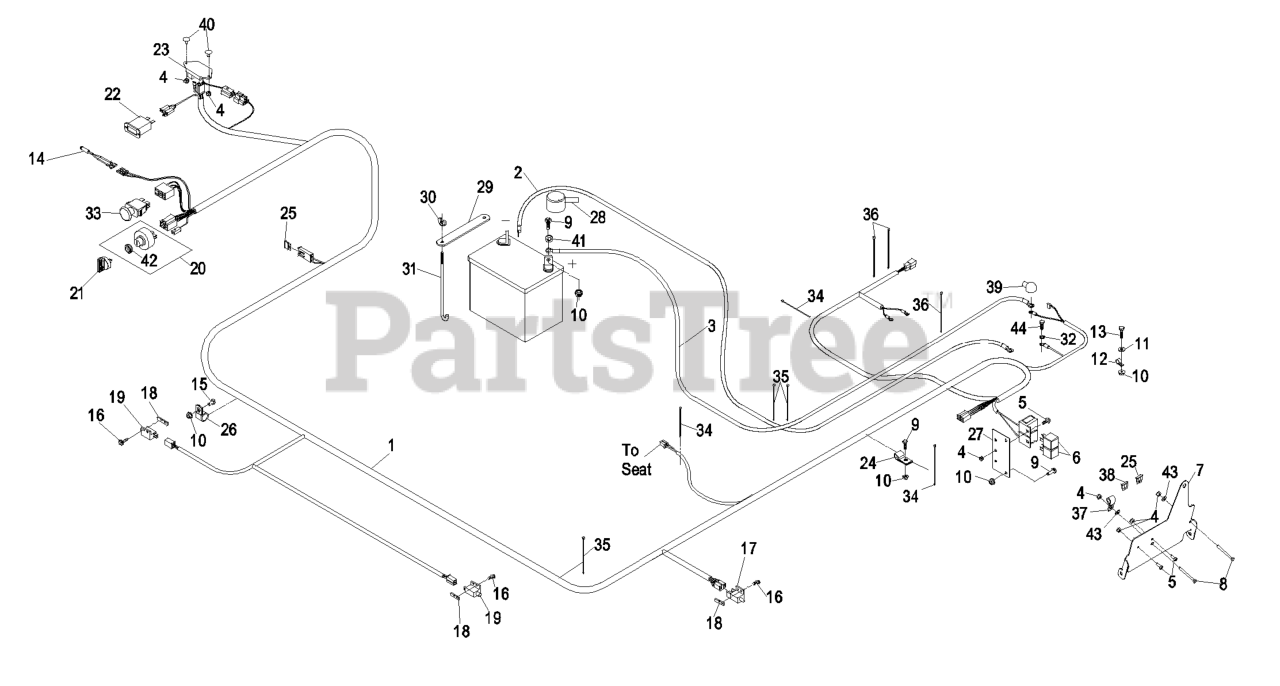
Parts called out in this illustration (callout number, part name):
1	HARNESS, WIRE LAZER EFI
2	WIRE-GROUND
3	ASM,POSITIVE BATTERY CABL
4	NUT-LOCK, NI
7	PANEL-EFI
8	SCREW-HH
9	SCREW-HH
11	WASHER-FLAT
12	CLIP-LOOM
13	SCREW-HH
14	INDICATOR-LED, RED
15	SCREW-HH
16	SCREW-PPH
18	PLATE-TAPPED
19	SWITCH-OPEN, NORMALLY
20	ASM,SWITCH W/NUT
21	KEY-IGNITION
22	METER-HOUR
23	MODULE-DELAY, SEAT
24	CLIP-LOOM
25	FUSE-BLADE TYPE, 20 AMP
26	CLIP-LOOM
27	MOUNT-RELAY
28	INSULATOR-BATTERY
29	STRAP-HOLDDOWN, BATTERY
30	WINGNUT
31	BOLT-HOLDDOWN
32	WASHER-PLAIN
33	SWITCH-PTO
34	TIE-CABLE
35	TIE-PLASTIC
36	TIE-PLASTIC
37	CLIP-LOOM
39	INSULATOR-SOLENOID
40	BOLT-CARR
41	WASHER-FLAT
42	NUT-SWITCH, IGNITION
43	WASHER-FLAT
44	SCREW-HH
